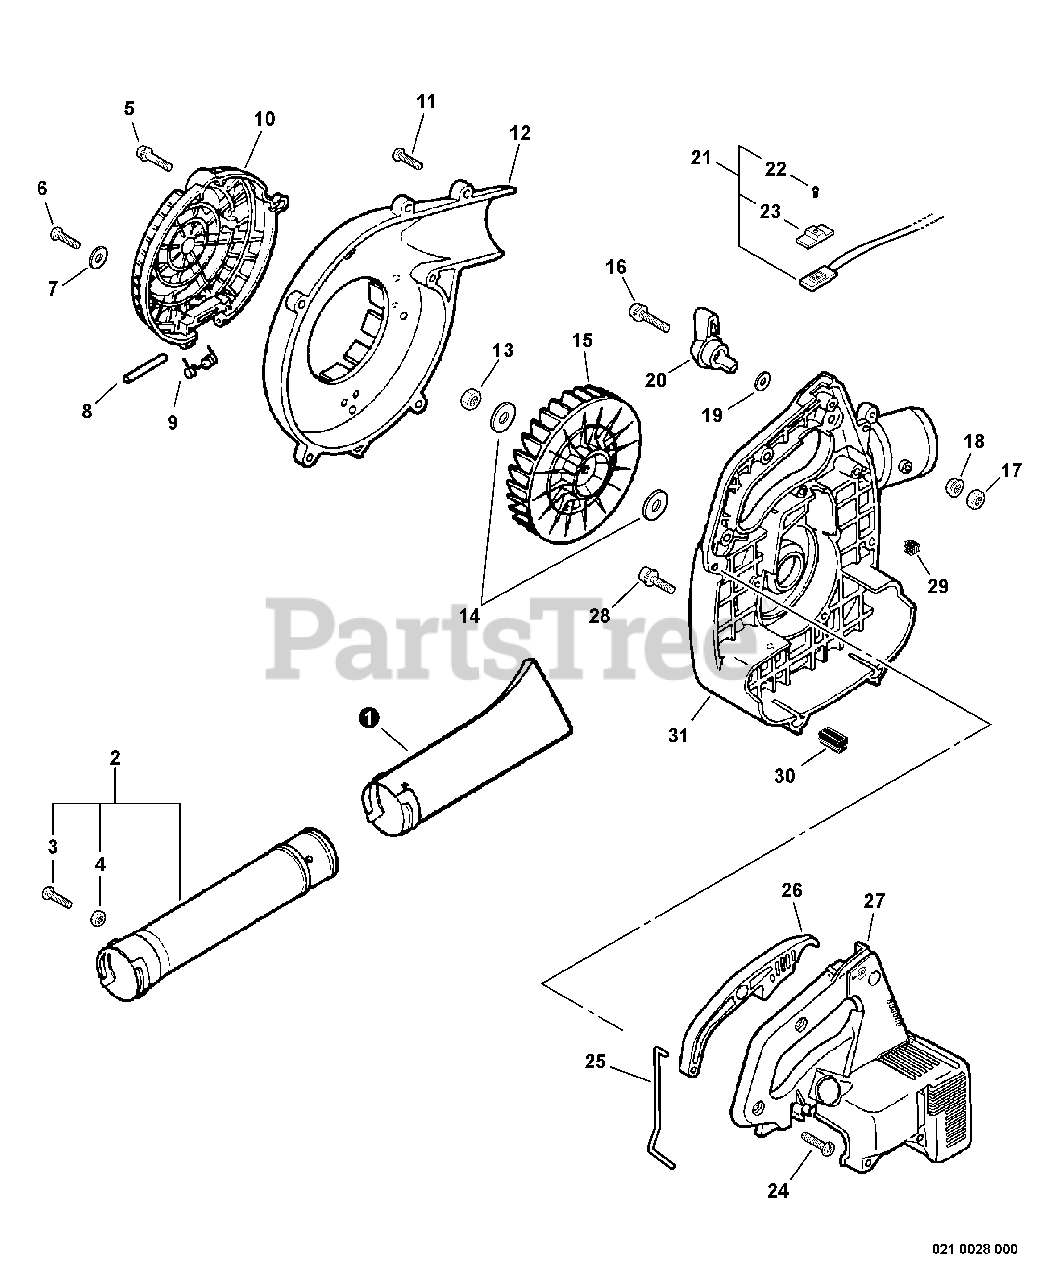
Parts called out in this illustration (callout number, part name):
1	TUBE, BLOWER - NOZZLE
2	TUBE, BLOWER - STRAIGHT
3	SCREW 5×10
4	NUT M5
6	SCREW 5×14
7	WASHER 5.5×12×0.8
8	PIN, INTAKE COVER
9	SPRING, COIL
10	COVER, INTAKE
11	SCREW, TAPPING 5×20
12	COVER, FAN
16	SCREW 5×25
18	NUT, FLANGE M5
19	WASHER 5.5×12×0.8
20	CONTROL, THROTTLE
21	IGNITION SWITCH ASSY
22	SCREW 3×10
23	KNOB, SWITCH - ORANGE
24	SCREW, TAPPING 5×20
25	ROD, THROTTLE
26	CONTROL, THROTTLE
27	COVER, ENGINE
28	SCREW 4×22
29	GROMMET, PLUG
31	COVER, FAN - RIGHT
